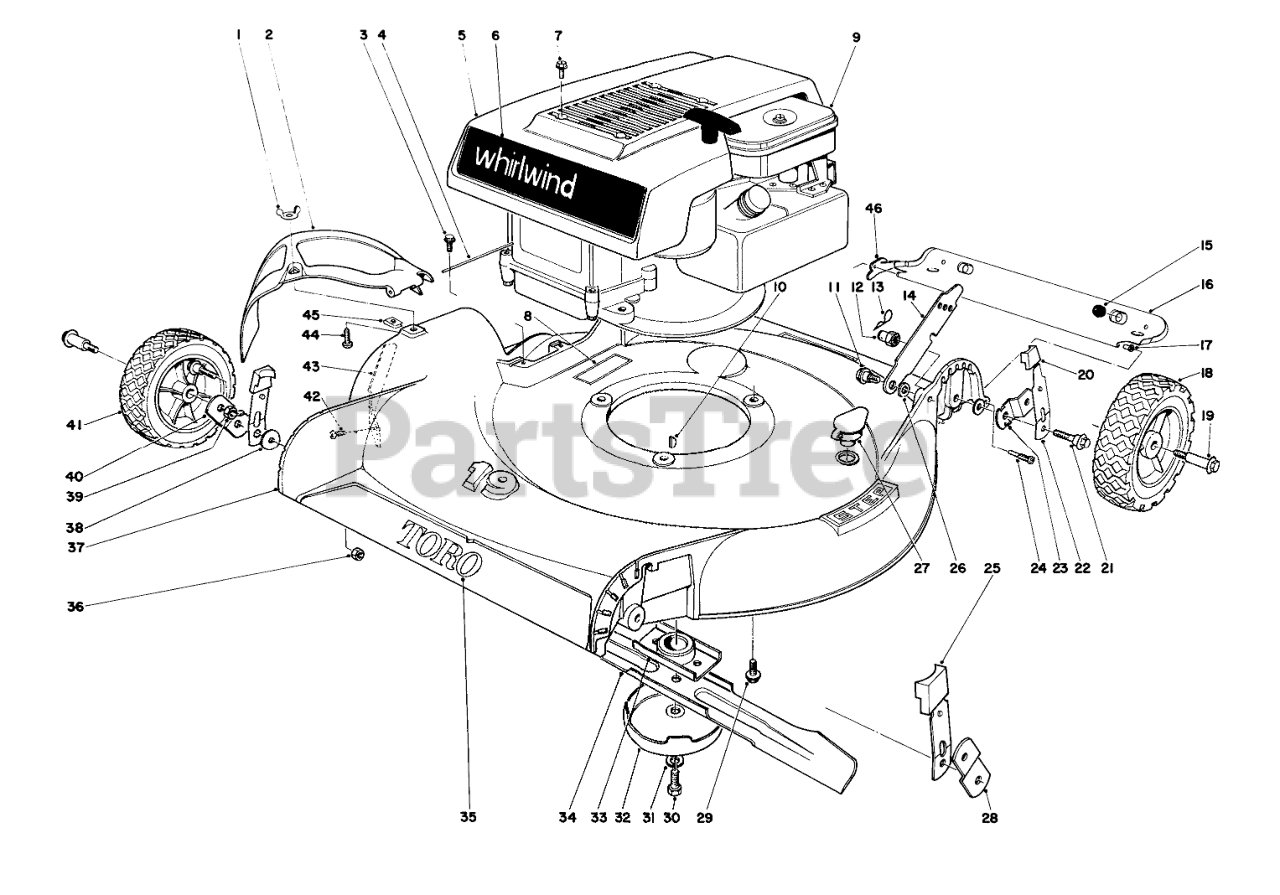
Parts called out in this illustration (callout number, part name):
1	NUT-WING SPECL
2	Deflector
3	SCREW
4	HINGE PIN
5	Shroud
6	Decal Whirlwind
7	8X1/2 SELF TAP SCREW
8	Decal
9	Engine (Model 16073)
10	KEY-WOODRUFF
11	SCREW-SHOULDER
12	HANDLE PIVOT NUT
13	PIN-COTTER, HAIR
14	Latch
15	SKID BUTTON
16	Safety Shield (Incl. Ref. #15 & 17) (Model 16073)
17	SAFTEY SHIELD BUSHING
18	WHEEL ASM 8
20	Arm Knob
21	PIVOT SCREW
22	Spring Arm
23	Pivot Arm
24	SAFTEY SHIELD SCREW
25	Arm Knob
26	SPACER
27	WASHOUT PLUG
28	Pivot Arm
29	SCREW-HWHTF
30	SPECIAL SCREW
31	WASHER-LOCK
32	AntiScalp Cup
33	BLADE RETAINER WA
34	Blade
35	Decal Toro
36	Nut
37	Housing (Model 16073)
38	WASHER-PIVOT
39	Nut
40	Pivot Arm
41	WHEEL ASM 7
43	Bar Safety
45	NUT-SPEED
46	Restraint R.H.
